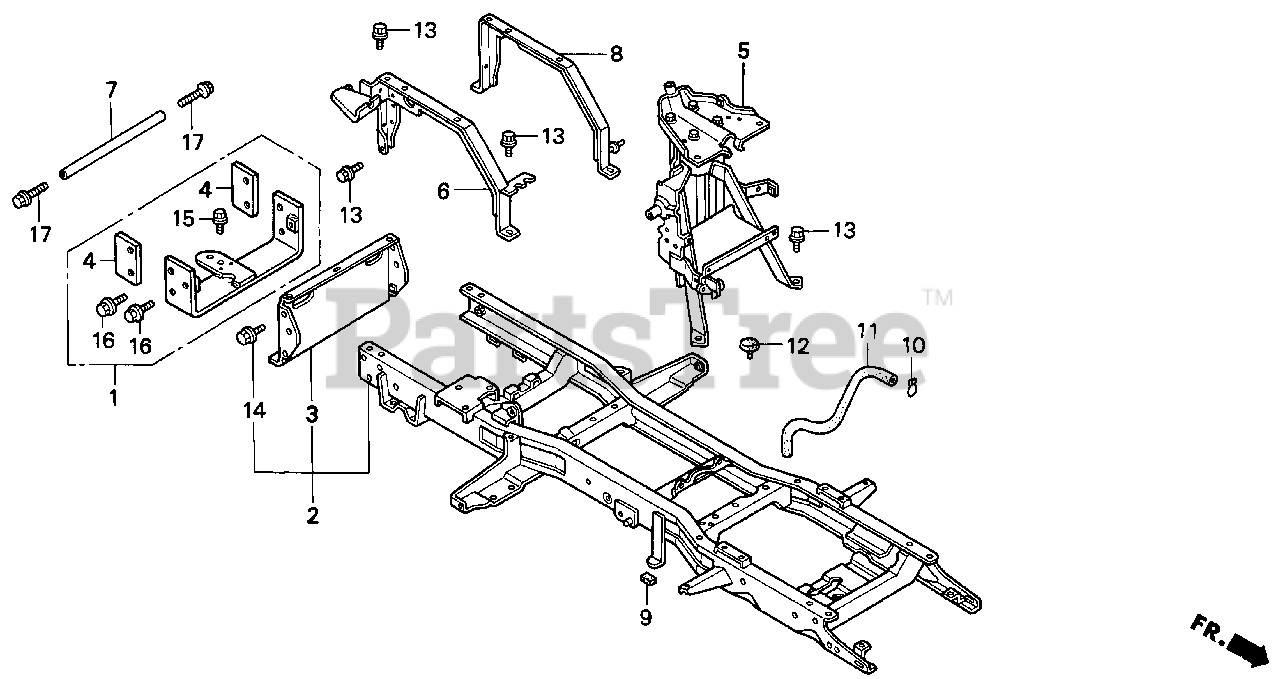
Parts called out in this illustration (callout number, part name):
1	HITCH KIT, TRAILER
3	HITCH, TRAILER
4	SPACER, TRAILER HITCH
5	COLUMN, STEERING
6	FRAME, R. RR.
7	STIFFENER, RR. FRAME
8	FRAME, L. RR.
13	BOLT, FLANGE (8X14)
14	BOLT, FLANGE (8X14)
15	BOLT, FLANGE (8X16)
16	BOLT, FLANGE (8X20)
17	BOLT, FLANGE (8X20)
